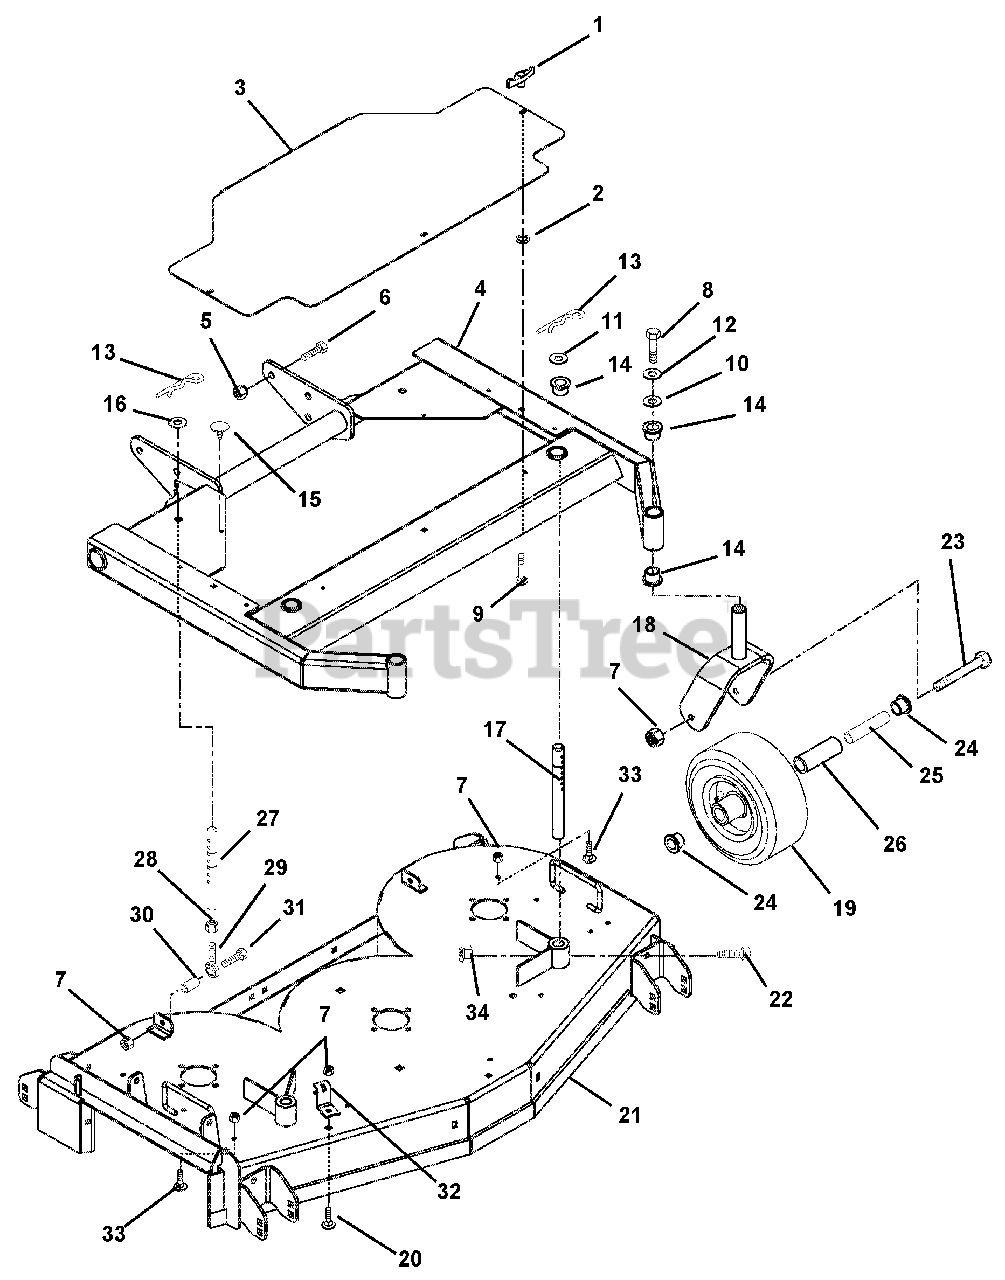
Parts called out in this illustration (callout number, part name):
1	Knob, Wing .312-18
2	Nut, Push .312
3	Cover, Belt Pro Mower
4	Weldment, Mower Frame 48" Floating (108, 125)
5	Nut, Locking-Nylon .625-11
6	Bolt, Hex .62-11 x 1.50
7	Nut, Locking-Top-Flange .38-16
8	Bolt, Hex .38-16 x 1.25 Grade 5
9	Bolt, Round Head Square Neck .31-18 x 1.00
10	Washer, Flat-Steel .38 x 1.50 x .125
11	Washer, Flat-Steel .875 x 1.50 x .120
12	Washer, Locking .38 x .094 Regular
13	Pin, Hair-Internal .17 x .68 x 3.50
14	Bushing, Flange 1.00 x 1.25 x 1.50 x 1.50
15	Bumper Grommet .125 x .25 Dia.
16	Washer, Flat-Steel .688 x 1.75 x .134
17	Rod, Front Height Adjustment
18	Weldment, Caster Fork
19	Wheel 9 x 3.50
20	Bolt, Round Head Square Neck .38-16 x 1.00 Grade 5
21	Kit, 48" Floating Mower Deck with Decals (108, 125)
22	Bolt, Hex .25-20 x 2.00 Grade 8
23	Bolt, Hex .38-16 x 5.50
24	Bearing, Retainer
25	Bearing .625 x .380 x 4.08
26	Bearing-Roller
27	Rod, Rear Height Adjustment
28	Nut, Jam .375-24
29	Rod End, .38 Right Hand
30	Bushing-Sleeve .377 x .624 x .37
31	Bolt, Hex .38-16 x 1.50 Grade 5
32	Anchor, Spring
33	Bolt, Round Head Square Neck .38-16 x .75 Grade 5
34	Nut, Locking-Top-Flange .25-20
